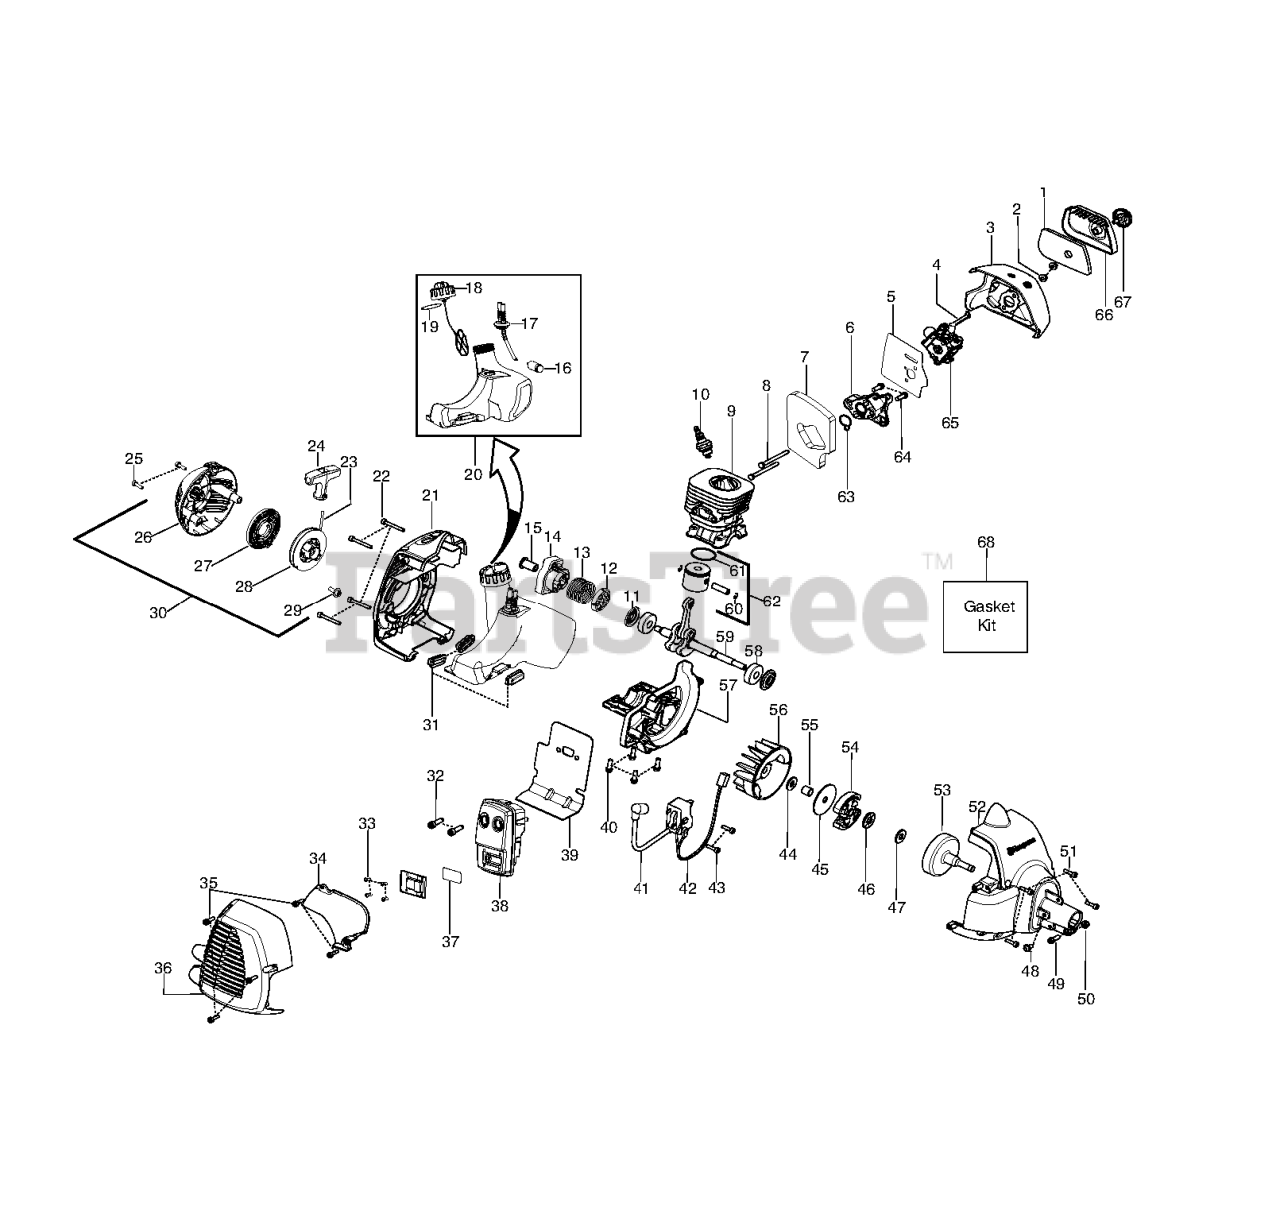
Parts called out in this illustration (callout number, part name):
1	FILTER AIRBOX
3	RP_AIR BOX
4	CHOKE LEVER
5	KIT GASKET CARB
6	CARB ADAPTOR
7	KIT GASKET 28CC
8	BOLT CARB ADAPTOR
9	CYLINDER
10	Plug - Spark (RCJ-8Y)
11	KIT SEAL CRANKSHAFT
12	WASHER STARTER
13	SPRING STARTER CUP
14	ASSY STARTER CUP
15	COUPLING STARTER
16	FUEL PICK-UP ASSY
17	KIT FUEL LINE
18	ASSY-CAP W/RETAINER
19	KIT GASKET 28CC
20	ASSY FUEL TANK HVA
21	REAR SHROUD
24	STARTER HANDLE GRAY
25	SCREW M5-0.8X30MM
26	STARTER HOUSING
27	%KIT STARTER SPRING
28	KIT STARTER PULLEY
30	ASSY-STARTER HSG.
31	ISOLATOR FUEL TANK
32	BOLT MUFFLER
33	SCREW-10-16 X 1/2 HI-LO
34	SHIELD HEAT
35	SCREW M4 X 1.75 PT 16MM
36	GUARD-MUFFLER
37	KIT SPARK ARRESTOR SCREEN
38	ASSY MUFFLER NC
39	KIT GASKET 28CC
40	SCREW-M5-0.8 X 25MM(TAP)
41	IGNITION MODULE MBU-7
42	ASSY MODULE LEAD WIRE
43	SCREW M4 X .70 TT 16MM
44	WASHER CLUTCH
45	WASHER-CLUTCH
46	BEARING THRUST
47	WASHER THRUST
50	LOCKNUT-HEX 10-24
51	SCREW M4 X .70 TT 16MM
52	FAN HSG ASSY
53	ASSY-CLUTCH DRUM
54	%KIT CLUTCH ASSY
55	SPACER FLYWHEEL
57	CRANKCASE CASTING
58	BEARING RADIAL BALL (6201)
59	KIT CRANKSHAFT ASSY
60	WRIST PIN RET.
61	RING PISTON
62	KIT PISTON 28CC TRIMMER
63	KIT GASKET 28CC
64	SCREW-M5-0.8 X 25MM(TAP)
66	COVER-AIR BOX
67	KNOB ASSY AIRBOX COVER
68	KIT GASKET 28CC
